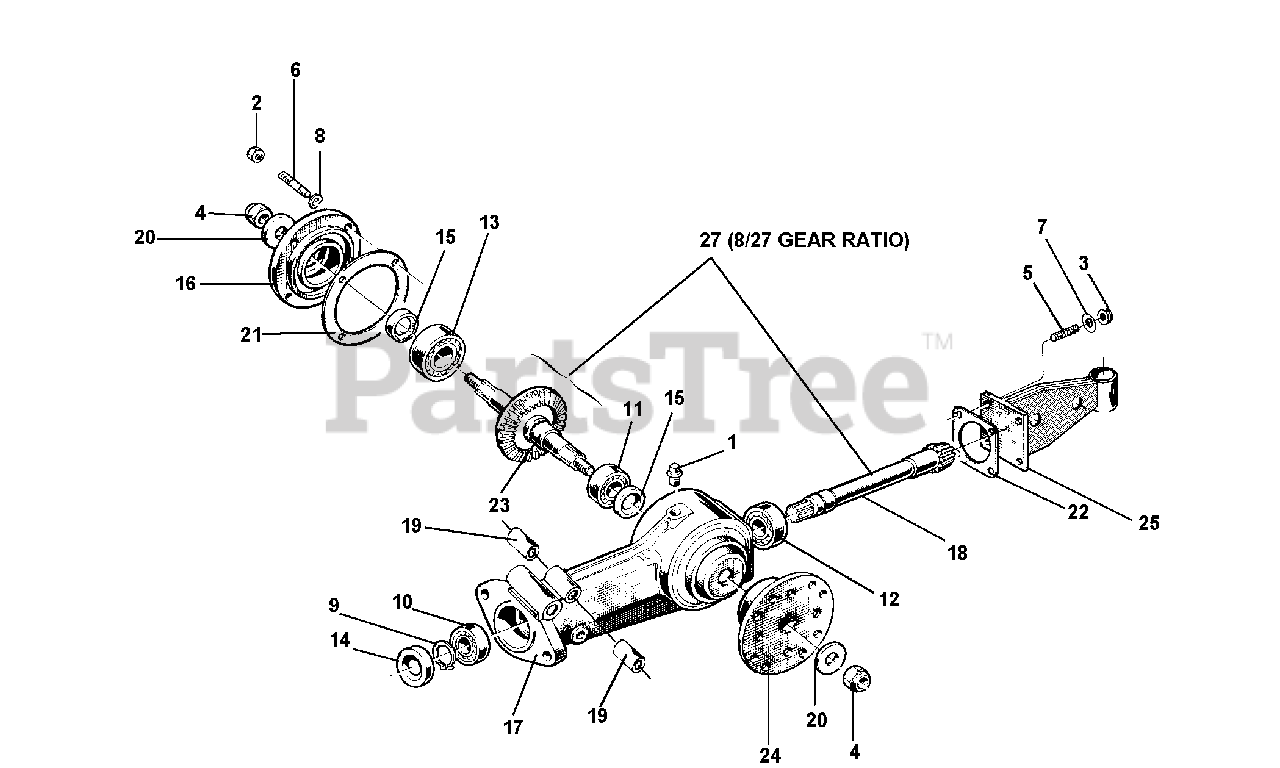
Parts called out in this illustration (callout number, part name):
2	NUT, SELF LOCKING M8
4	NUT, SELF LOCKING M14 STANDARD
5	STUD M8 X 32 X 14 X 14
6	STUD M8 X 38 X 14 X 14
7	SUPER WASHER 8 DIN
8	WASHER, LOCK 8.4
9	CIRCLIP EXTERN. D 20
10	BEARING 20 X 42 X 12 6004
11	BEARING 25 X 52 X 15 6205
12	BEARING 20 X 47 X 14 7204 B
14	OIL SEAL 20 X 42 X 7 STANDARD
17	ROTARY HOE CENTRAL ASSEMBLY
18	PINION SHAFT
22	ROTARY HOE GASKET
23	SHAFT WITH GEAR
24	BLADE HOLDER FLANGE
25	REAR COVER FOR ROTARY HOE
26	GEAR BOX COMPLETE/ROCKGUARD
27	PINION AND GEAR SHAFT SET
